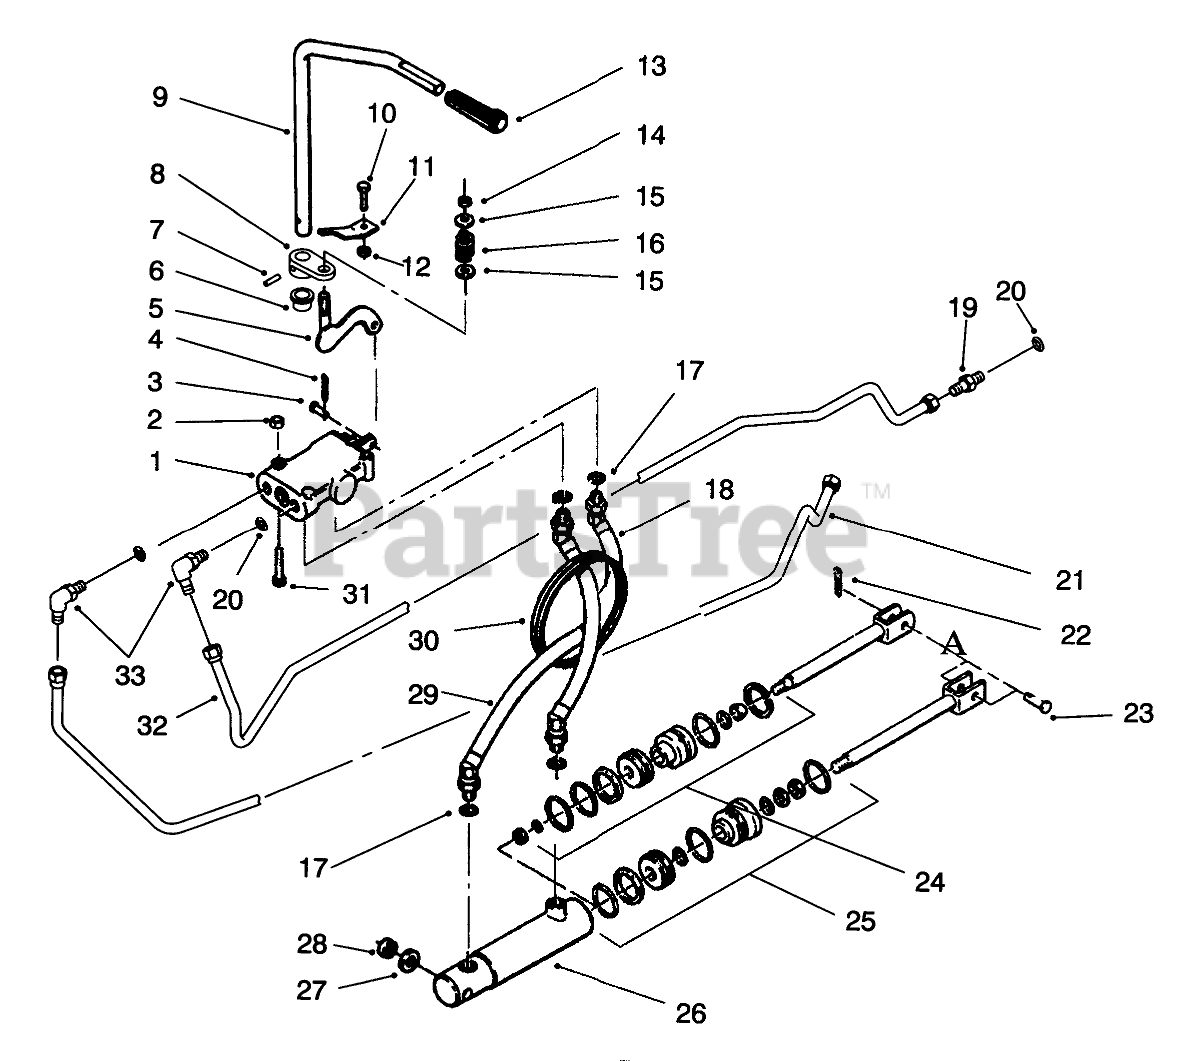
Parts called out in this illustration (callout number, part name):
1	Valve-Hydraulic (Incl. Ref. #3-4)
2	NUT-LOCK, NI
3	PIN-CLEVIS
4	PIN-COTTER
5	WLDMT-LIFT BAR
6	NYLINER BUSHING
7	SPIROL PIN 7/32X7/8
8	ARM-CONTROL
9	ROD-LIFT CONTROL
10	SCREW-HH
11	BRACKET-CONTROL R B
12	NUT-LOCK, NI
13	KNOB-HYDRAULIC LIFT
14	NUT-LOCK, NI
15	WASHER-PLAIN
16	SPRING
17	O RING
18	Hose ASM-Hydraulic
19	Fitting-Straight Adapter (Incl. Ref. #20)
20	0-Ring
21	TUBE-HYD PRESSURE
22	PIN-COTTER
23	Pin-Clevis
24	S/A O-RING&GASKET AS
25	S/A 108872 HYD CYL
26	Cylinder-Hydraulic (Incl. Ref. #24-25)
27	Washer
28	SPACER-OUTER
29	Hose ASM-Hydraulic
30	GROMMET
31	SCREW-HH
32	TUBE-HYD RETURN
33	Fitting-90 Deg. (Incl. Ref. #20)
